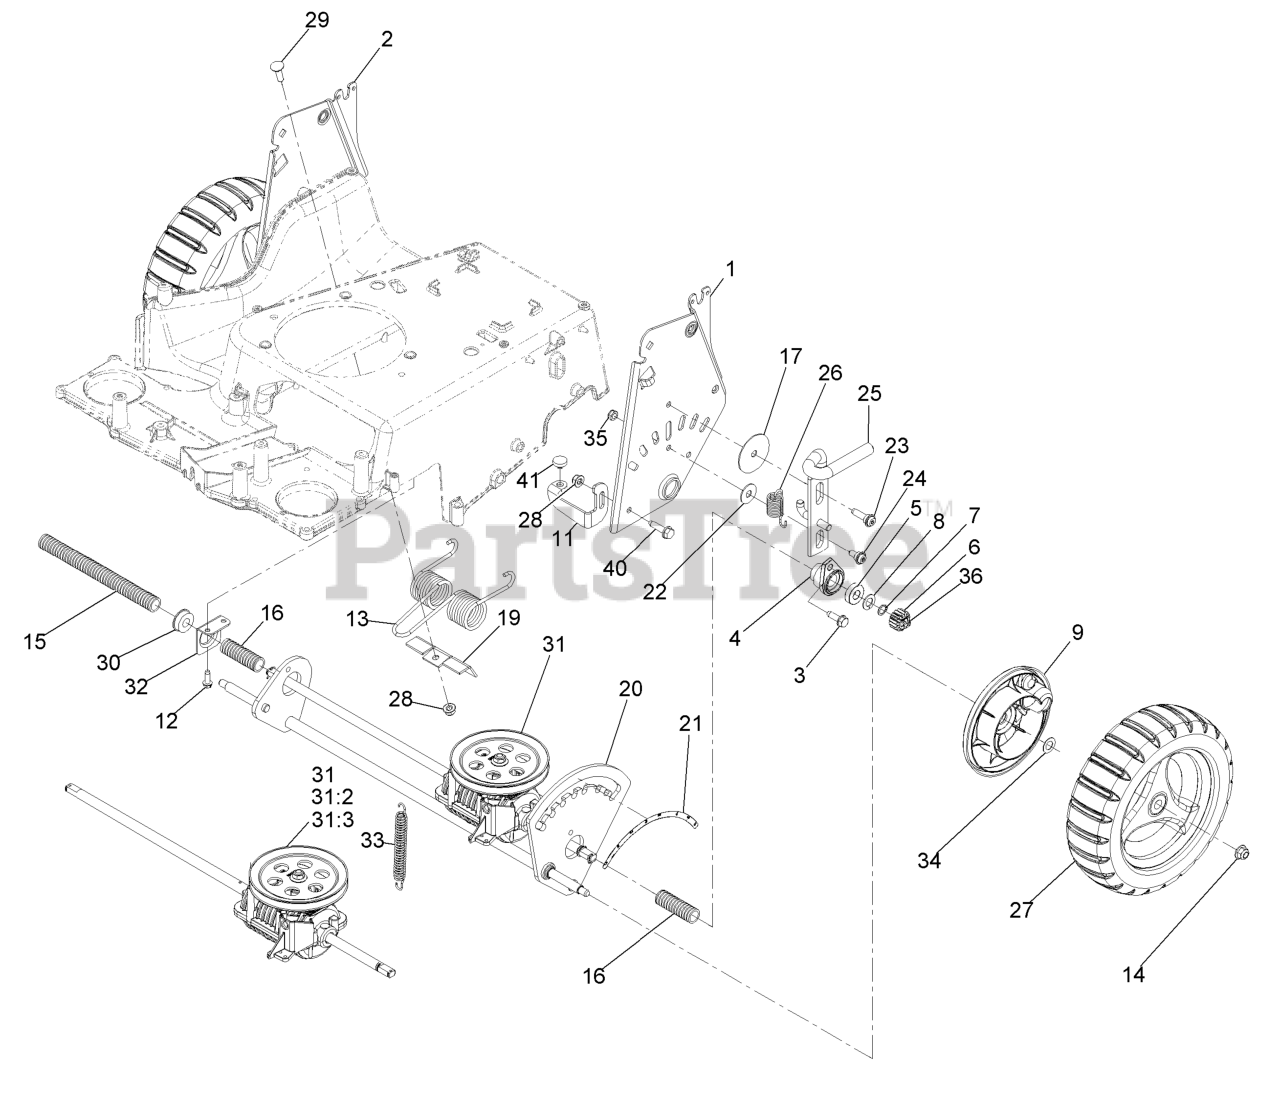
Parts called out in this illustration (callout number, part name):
1	LH HOC Plate ASM
2	RH HOC Plate ASM
3	Screw-HWH 5/16-18 X 1 Tf
4	Retainer-Bearing
5	Bearing-Ball
6	Gear-Pinion, 15T
7	Ring-Retaining
8	Washer-Thrust
9	Cover,Gear
11	Bracket-Stop, Adjustable
12	Screw-HWH 1/4-20 X 3/4 Tf
13	Spring-Torsion
14	Nut-Nyloc 3/8-16 Flg
15	Conduit-Convoluted
16	Conduit-Convoluted
17	Washer-Plain
19	Bracket
20	Axle-Rear
21	Decal-HOC, Rear
23	Screw-Button Head 5/16-18 X 1 Tf
24	Screw-Shoulder Bh 5/16-18 X 1/2 Tf Torx
25	Lock-Height, Adjust
26	Spring-Extension
27	Wheel ASM, 10.5 W/Gear
28	Nut-Nyloc 5/16-18 Flg
29	Bolt-Carriage 5/16-18 X 1
30	Bearing-Ball
31	Transmission Kit
31:2	Pin-Snap
31:3	Ring-Retaining
32	Mount-Bearing
33	Spring-Extension
35	Nut-Nyloc 5/16-18 Thin
36	Pin-Snap
40	Screw-HWH 5/16-18 1 1/4 Tf
